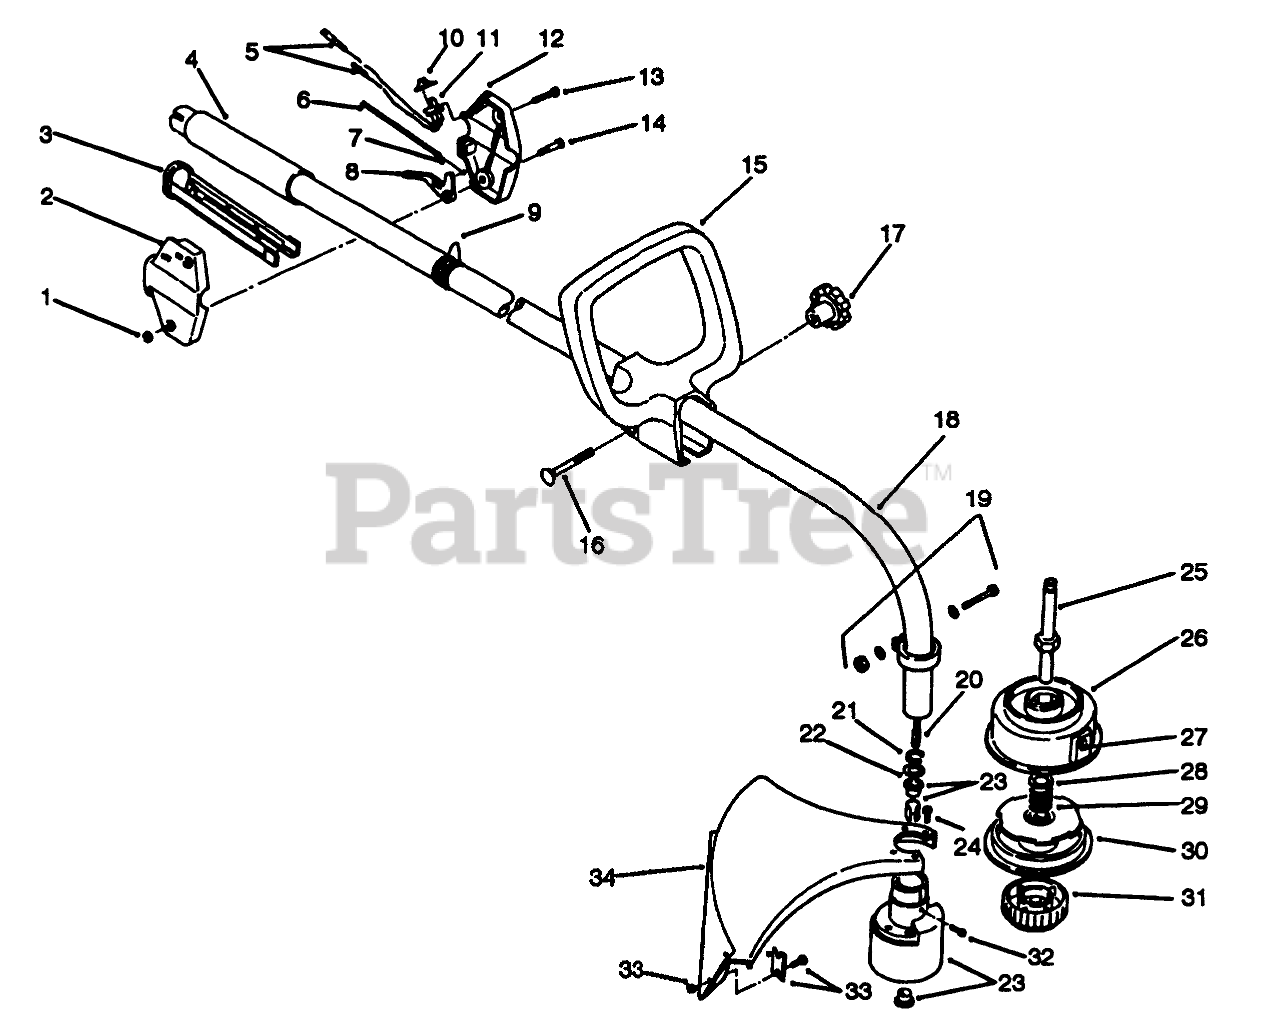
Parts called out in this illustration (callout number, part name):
1	NUT-LOCK, NI
2	RH HOUSING
3	TROUGH 1"
4	GRIP - RUBBER
5	LEAD WIRE ASM
6	Assy.-Throttle Cable
7	THROTTLE CABLE
8	THROTTLE LEVER
9	Clip-Shoulder Strap
10	SWITCH COVER
11	SWITCH
12	LH HOUSING
14	SCREW-SHOULDER
15	HANDLE SECONDARY
16	BOLT-CARRIAGE
18	DRIVE SHAFT HSG ASM
19	CLAMP ASM - UPPER
20	Drive Shaft
21	RETAINING RING
22	WASHER
23	BUSHING HSG ASM
24	GUARD MTG SCREW ASM
25	Shaft-Spool
26	OUTER SPOOL EYELET ASM
27	EYELET
28	RETAINER WASHER(SET OF 10)
29	SPRING
30	REEL - INNER
31	SMALL BUMP KNOB ASM
32	ANTI-ROTATION SCREW
33	Assembly-Blade (Incl. 2 Screws/2 Nuts)
34	Assembly-Guard & Blade (Incl. Ref. No.33)
